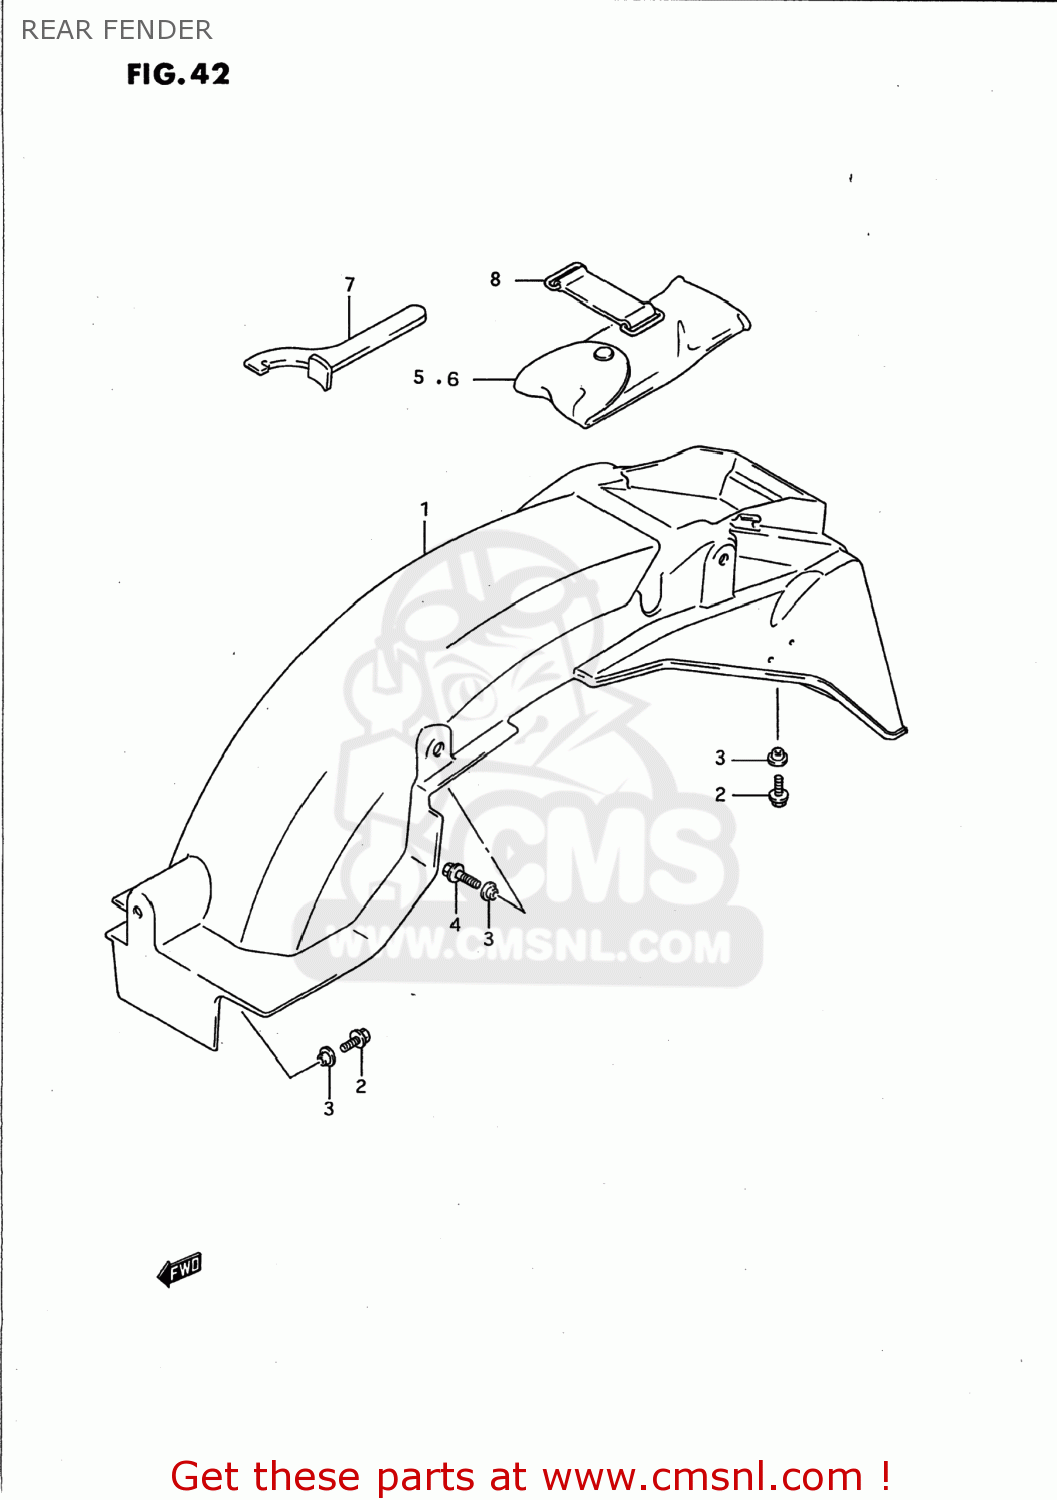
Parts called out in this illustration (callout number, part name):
1	BODY,RR FENDER
2	SCREW(6X10)
3	WASHER
4	BOLT
5	TOOL ASSY
6	TOOL ASSY
7	CLAMP
8	BAND
9	OWN MAN GSX750F
